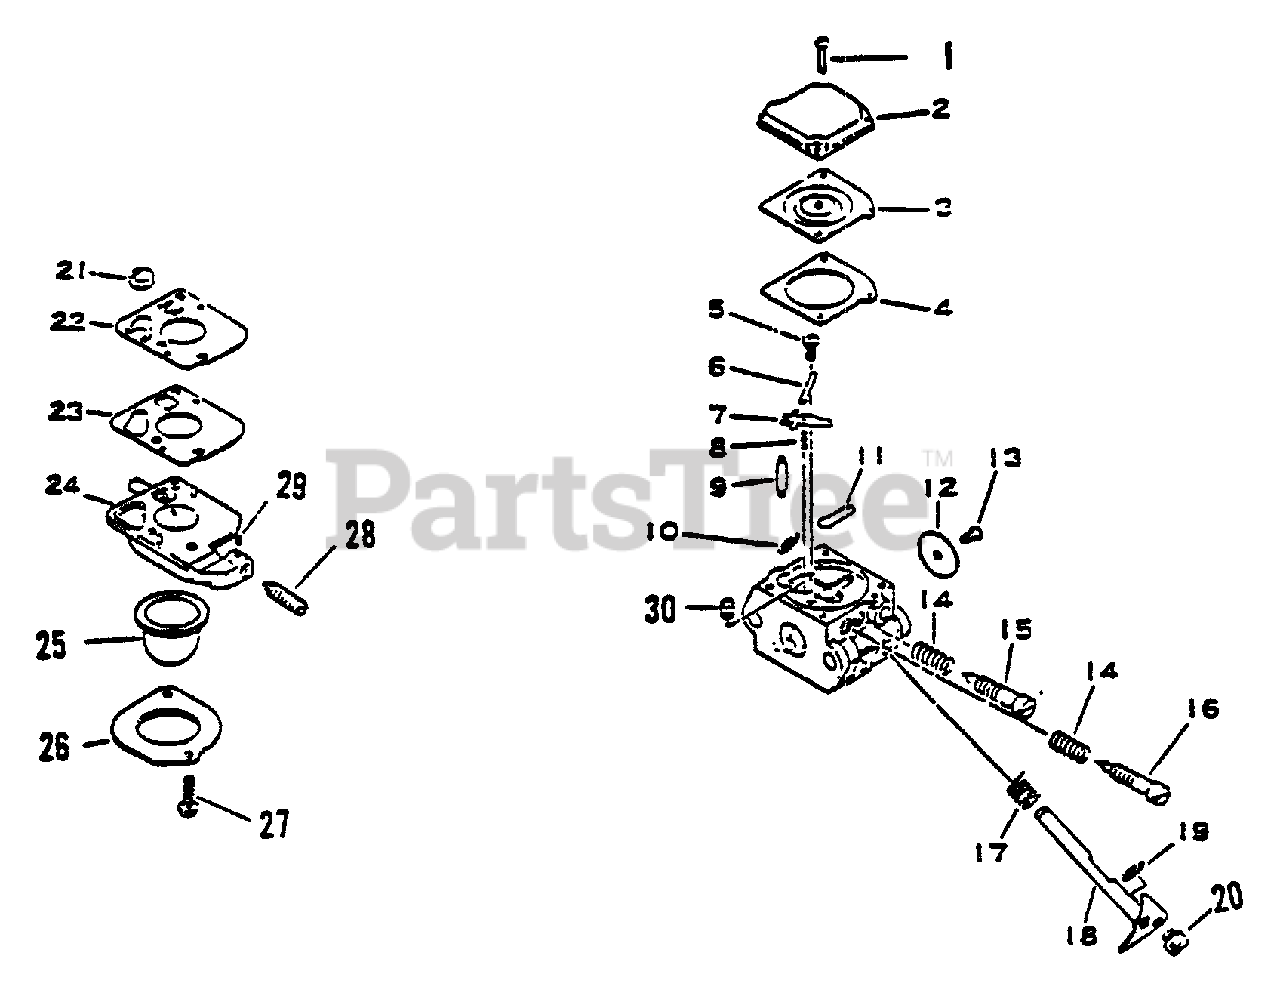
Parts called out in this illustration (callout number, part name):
2	COVER, DIAPHRAGM
3	DIAPHRAGM
4	GASKET, METERING
5	SCREW
6	PIN
7	LEVER, METERING
8	SPRING
9	VALVE, NEEDLE
11	PLUG, WELCH
12	VALVE, THROTTLE
14	SPRING, NEEDLE
15	NEEDLE, HIGH SPEED
16	NEEDLE, LOW SPEED
17	SPRING, THROTTLE RETURN
18	SHAFT, THROTTLE
21	STRAINER
22	DIAPHRAGM, FUEL PUMP
24	COVER, PUMP
25	BULB, PURGE
26	RETAINER
28	SCREW, IDLE ADJUST
29	PIECE, FRICTION
30	NOZZLE, CHECK VALVE
